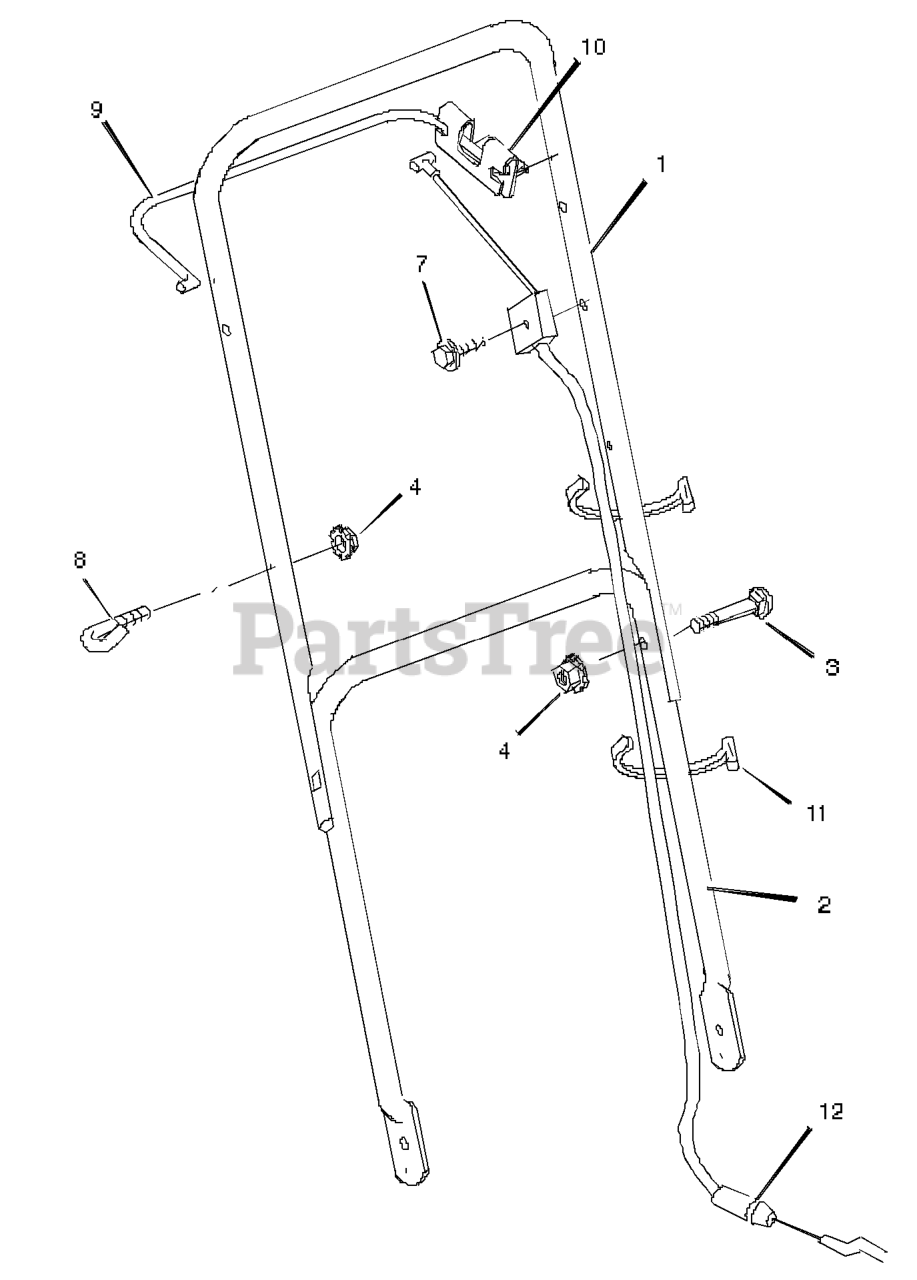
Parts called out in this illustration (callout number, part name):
1	Handle, Upper
2	Handle, Lower
4	Locknut
8	GUIDE, ROPE
9	Lever, Engine Stop
10	Bracket, Stop Lever
11	Fastener, Cable
12	Engine Stop Cable
